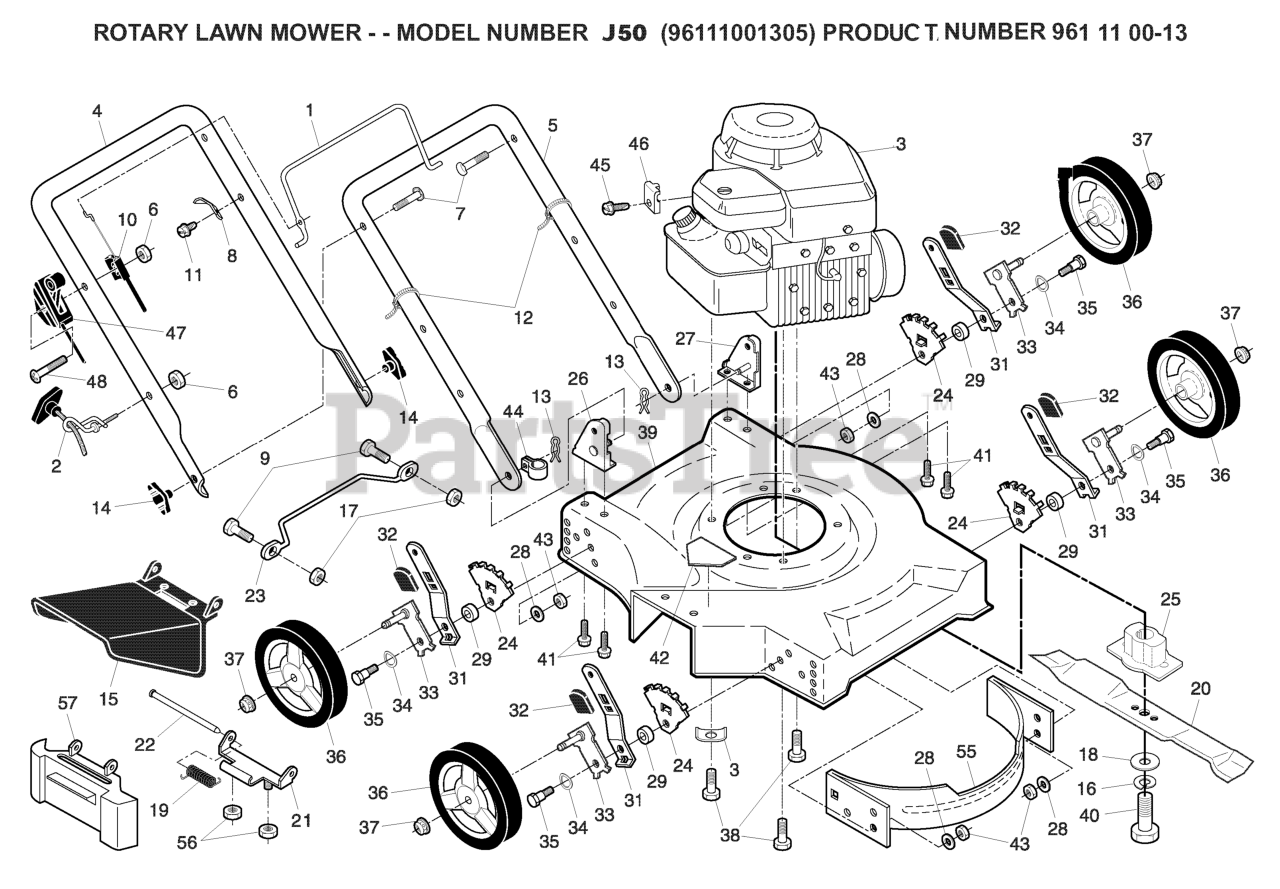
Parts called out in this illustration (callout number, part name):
1	BAIL.CONT.D.STRAIGHT.PUSH.BLK
2	RB GUIDE.ROPE.STD.BLK.ZIN WSL
3	WASHER.ENGINE.BZP
5	HANDLE
6	NUT
7	BOLT, HANDLE 5/16-18X1.75
8	BRACKET UPSTOP
9	REPL BY 817 02 10-08
10	CABLE.CONTROL.MZR.RH.SP/PUSH
12	TIE GUIDE
13	HAIRPIN COTTER
14	KNOB, DEFLECTOR
16	LOCKWASHER
18	WASHER,HARDEN
19	SPRING.SIDE.DISCHARGE
20	BLADE.20.MULCH.(50DK,6020MD)
21	HINGE DEFLECTOR
24	BRACKET.ADJ.WHEEL.5POS.ADS
25	BLADE ADAPTOR
26	HANDLE BRACKET ASM. RH
27	HANDLE BRACKET ASM. LH
28	WASHER
29	SPACER.HEIGHT.ADJUSTER
31	SELECTOR SPRING, FRONT
33	AXLE ARM ASSY.
34	WASHER.CURVED.CYLINDRICAL
35	SHOULDER BOLT 5/16-18
36	WHEEL AND TIRE ASSY, REAR
37	NUT.HEX.FLANGE.3/8-16.LO(3 2)
38	BOLT 3/8-16X1-1/8
40	SCREW, HEX HD 3/8-24 X 1-3/8
41	SCREW.5/16-18X3/4
42	DECAL.INTERNATIONL.CUTFINGER
43	NUT.CENTERLOCK.5/16-
44	CLIP.CABLE.BLK
45	SCREW.HEX.HEAD.WASHER.10-16
46	CABLE CLAMP(ENGINE)
47	THROTTLE CONTROL
55	FRONT BAFFLE
56	LOCKNUT.NYLOC.1/4-20
57	PLATE.MULCHER.20.ECONOMY.BLK.
